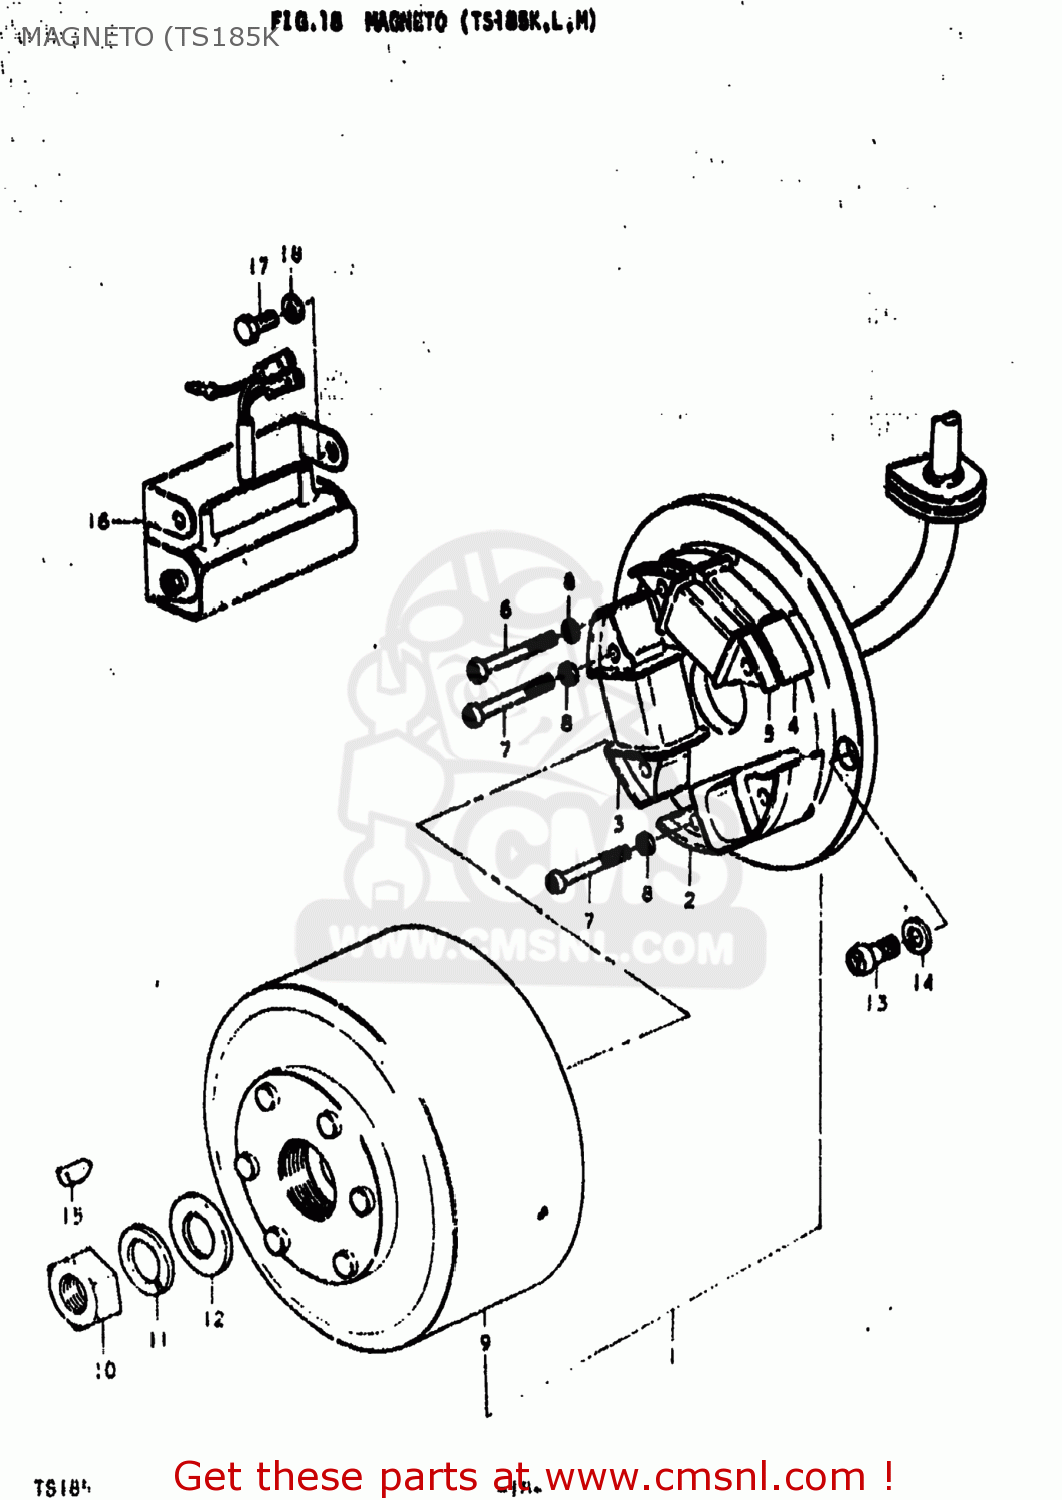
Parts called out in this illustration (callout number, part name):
1	MAGNETO ASSEMBLY
2	COIL,LIGHTING
3	COIL
4	COIL
5	COIL,PULSER
6	SCREW 5X35
7	SCREW
8	LOCK WASHER
9	ROTOR ASSEMBLY
10	NUT
11	LOCK WASHER
12	WASHER(14X27X3)
13	SCREW
14	WASHER
15	KEY 4MM
16	REGISTER ASSY,S
17	BOLT
18	LOCK WASHER
